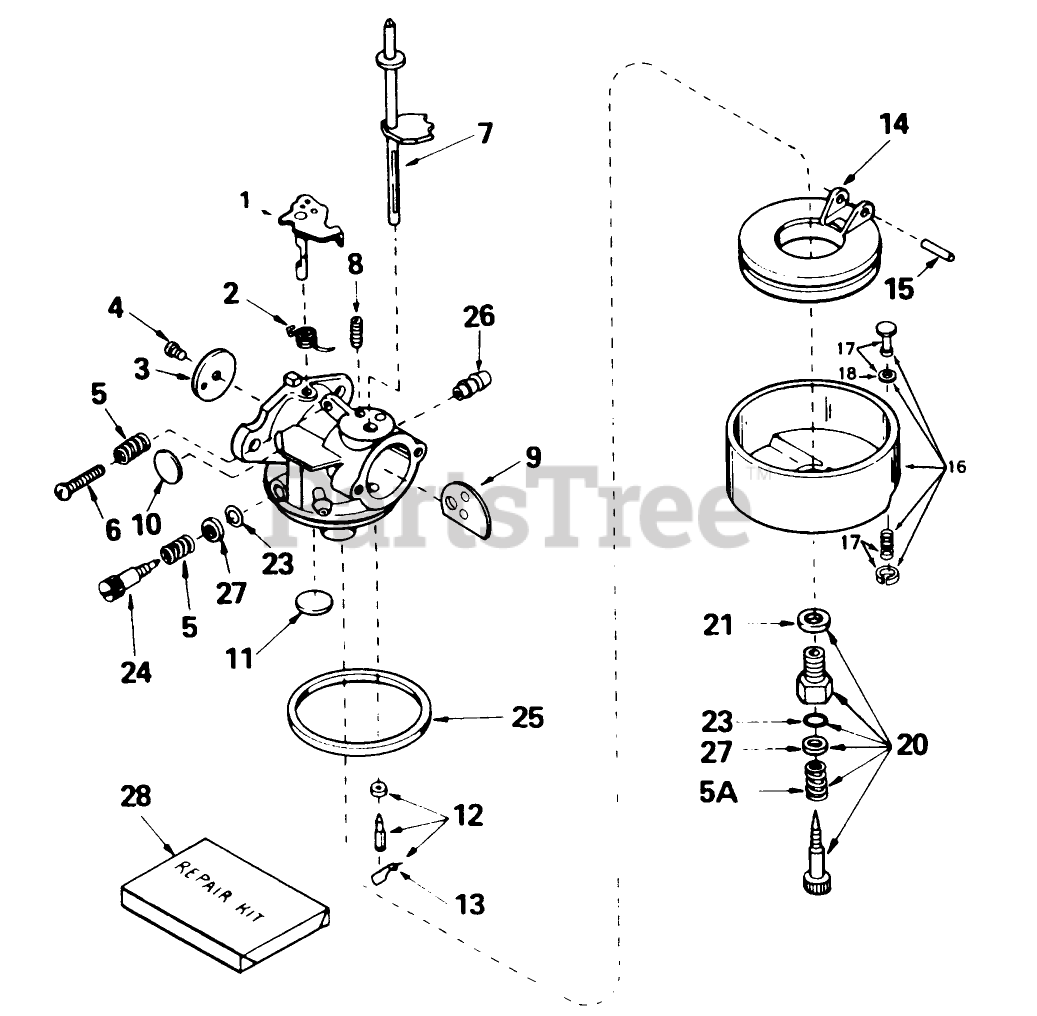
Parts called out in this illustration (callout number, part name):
1	Shaft/Lever-Throttle
2	Spring-Return, Throttle
3	Shutter-Throttle
4	Screw-Shutter
5	Spring-Tension
5A	Spring
6	Screw-Throttle Crack Screw / Idle Speed
7	Shaft-Choke
8	Spring-Positioning, Choke
9	Shutter-Choke
10	Plug-Welch, Idle Mixture Well
11	Plug-Welch, Atmospheric Vent
12	Inlet Needle, Seat Clip Assy. (Incl. No. 13)
13	Clip-Spring
14	Float
15	Shaft-Float
16	Float Bowl Asm. (Incl. Ref. # 32, 33)
17	Bowl Drain ASM
18	Gasket-Plunger, Drain
20	Adjustment Screw Assy., Main (Incl. Nos. 5A, 21 23)
21	Washer-Bowl Nut
23	ORing
24	Screw-Idle
25	O Ring-Bowl, Float
26	Fitting-Fuel
27	Washer
28	Repair Kit (Incl. items marked *)
